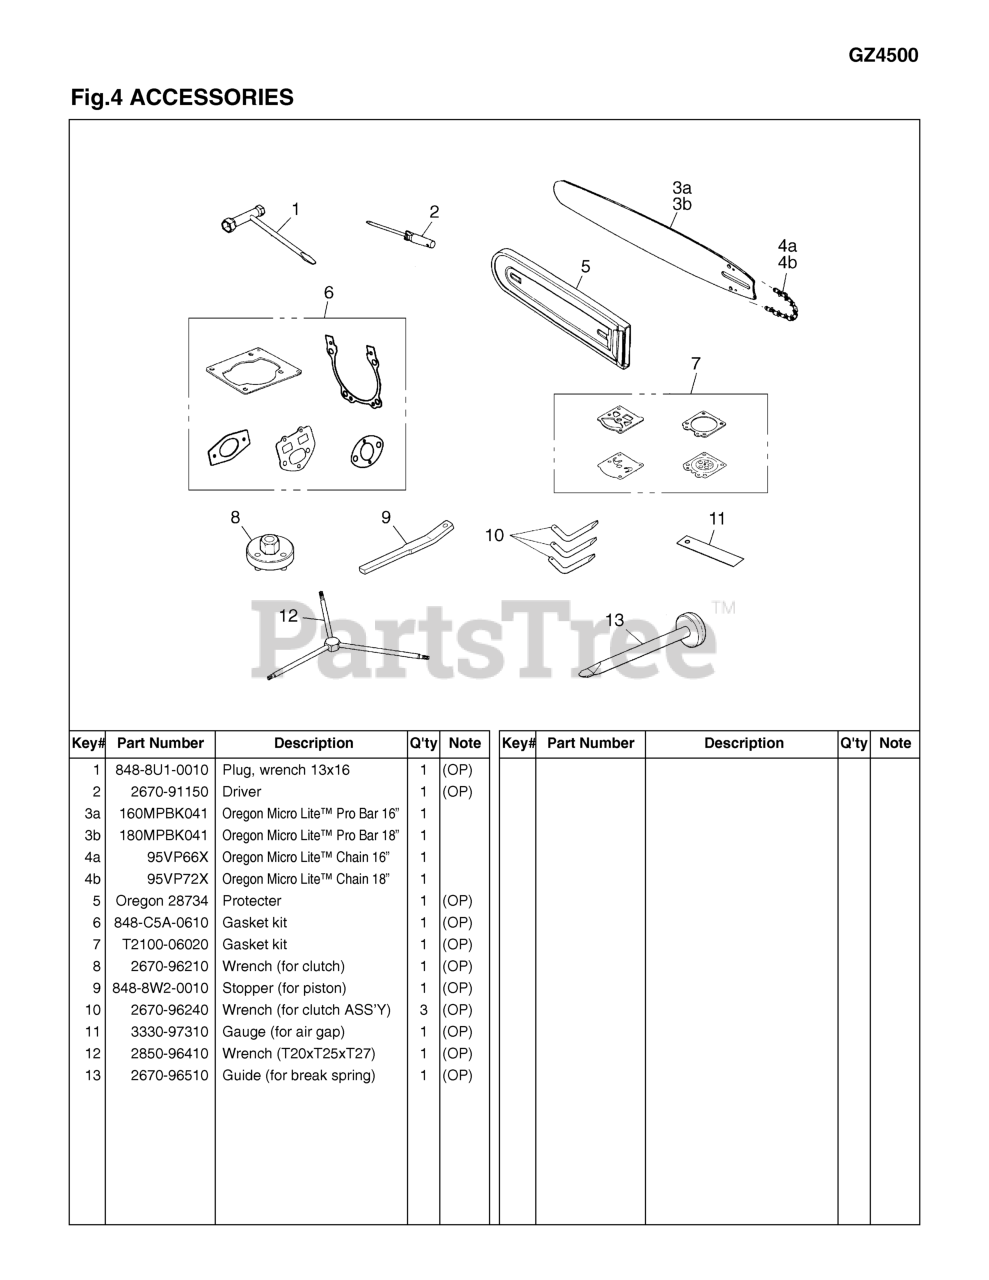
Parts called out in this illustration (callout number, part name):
1	WRENCH
2	SCREWDRIVER
3A	OREGON MICRO LITE PRO BAR 16
3B	OREGON MICRO LITE PRO BAR 18
4A	CHAIN 16
4B	OREGON MICRO LITE CHAIN 18
6	GASKET KIT
7	KIT, GASKET (G3800AVS)
8	WRENCH (TOOL)
9	STOPPER
10	WRENCH (TOOL)
11	GAUGE (TOOL)
12	WRENCH (RPLS. 2670-96410)
13	GUIDE (TOOL)
